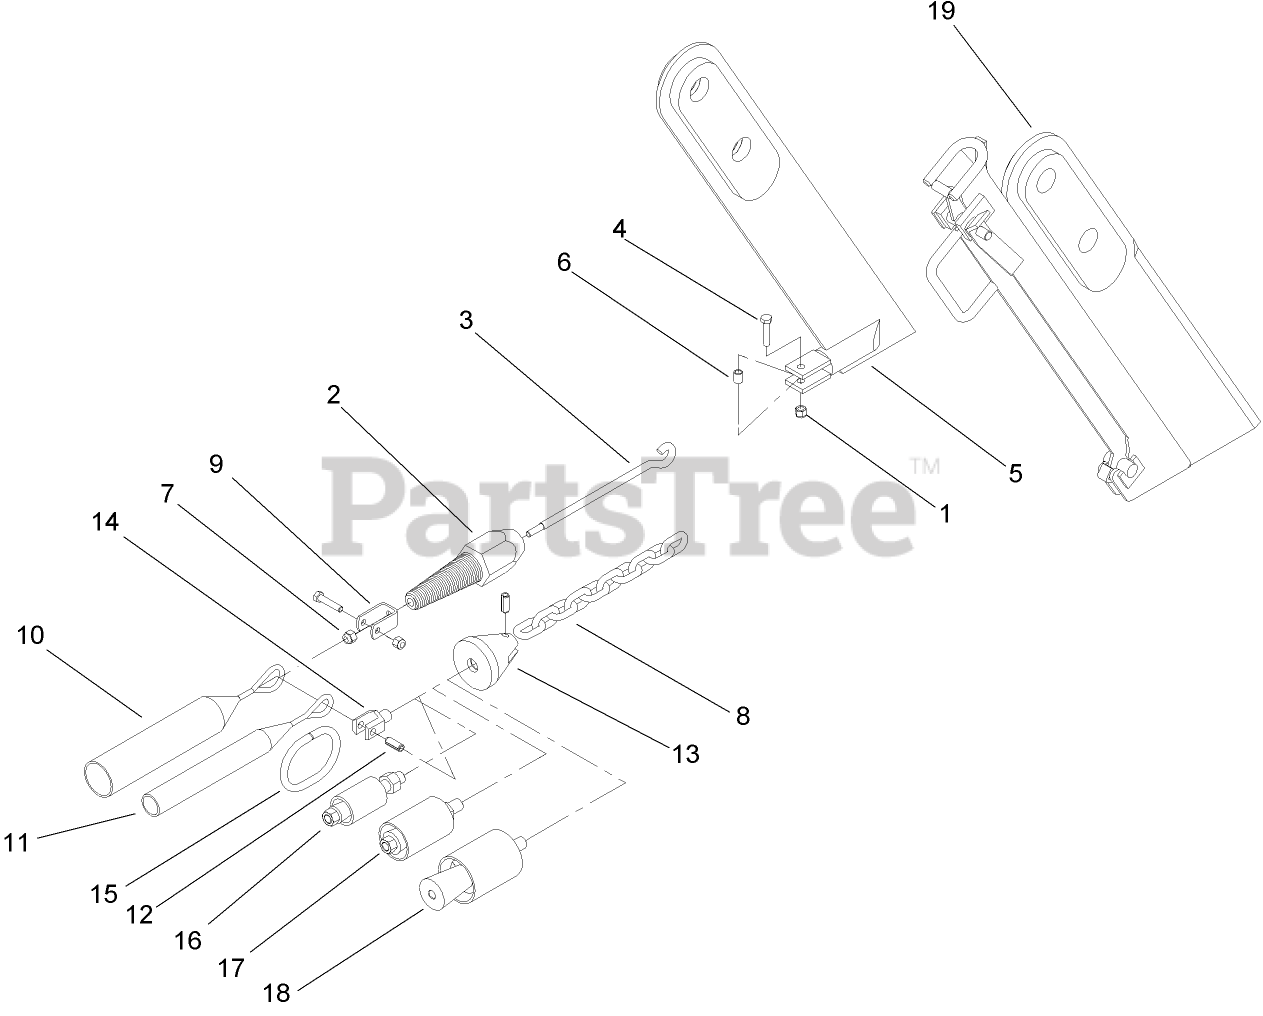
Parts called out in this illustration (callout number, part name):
1	NUT-LOCK, NI
2	PULLER-PIPE
3	CHAIN ASM
4	SCREW-HH
5	PLOW BLADE ASM (.38 X 12)
5	PLOW BLADE ASM (.25 X 12)
5	PLOW BLADE ASM (.5 X 18)
5	PLOW BLADE ASM (.38 X 18)
6	SPACER
7	NUT-LOCK, NI
8	CHAIN
9	CLEVIS
10	BASKET-GRIP (1.25-1.5)
11	BASKET-GRIP (.75-1.25)
12	PIN-ROLL
13	BULLET-PULLER
14	ADAPTER-CHAIN
15	LINK-WIRE
16	PULLER ASM (1 INCH)
17	PULLER ASM (1.5 INCH)
18	PULLER ASM (2 INCH)
19	CHUTED BLADE ASM
